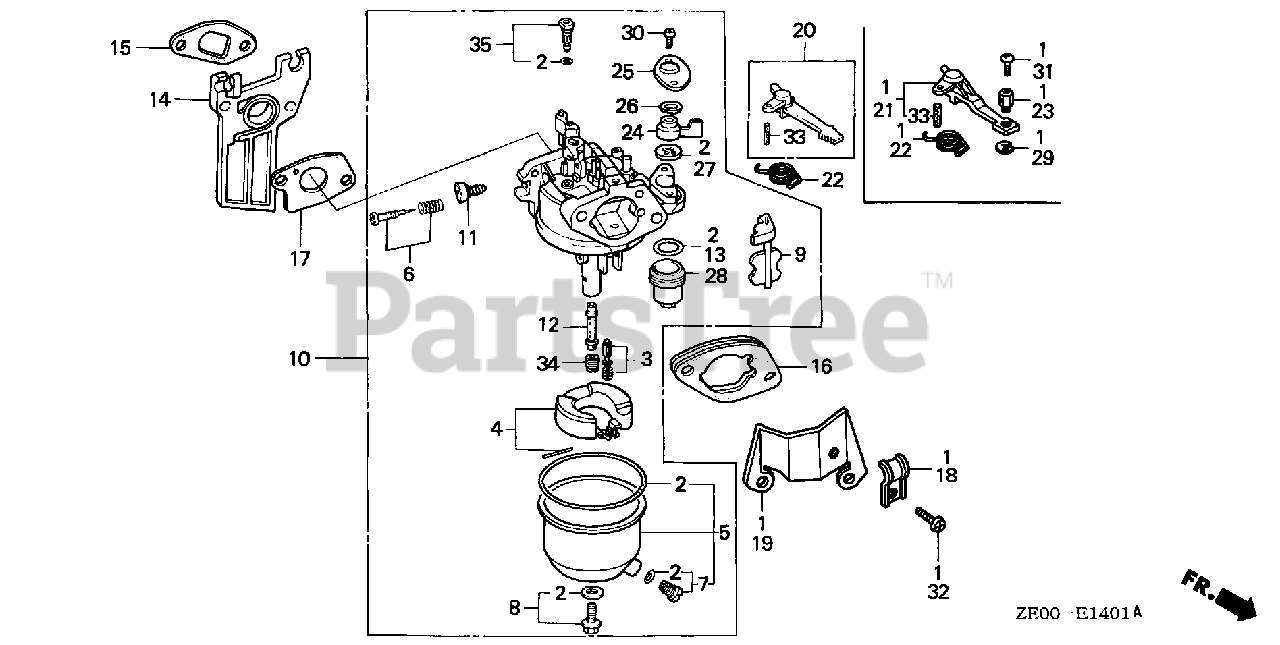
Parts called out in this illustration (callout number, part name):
2	GASKET SET
3	VALVE SET, FLOAT (SEAT NOT INCLUDED)
4	FLOAT SET
5	CHAMBER SET, FLOAT
6	SCREW SET, PILOT
7	SCREW SET, DRAIN
8	SCREW SET
9	CHOKE SET
9	CHOKE SET (NOT AVAILABLE)
10	CARBURETOR ASSY. (BE01B G) (W/STRAINER)
10	CARBURETOR ASSY. (BE01C A)
10	CARBURETOR ASSY. (BE01C C)
10	CARBURETOR ASSY. (BE01C D) (NOT AVAILABLE)
10	CARBURETOR ASSY. (BE01C F)
11	SCREW, THROTTLE STOP
12	NOZZLE, MAIN (NOT AVAILABLE)
12	NOZZLE, MAIN
13	GASKET, FUEL STRAINER CUP
14	INSULATOR, CARBURETOR
15	GASKET, INSULATOR
16	SPACER, CARBURETOR
17	GASKET, CARBURETOR
20	LEVER, CHOKE (STD)
24	LEVER, VALVE
25	PLATE, LEVER SETTING
26	SPRING, PETCOCK LEVER
27	GASKET, PETCOCK
28	CUP, FUEL STRAINER
30	SCREW, PAN (3X8)
33	PIN, SPRING (2X12)
34	JET, MAIN (#55)
34	JET, MAIN (#58)
34	JET, MAIN (#60)
34	JET, MAIN (#62)
35	JET SET, PILOT (#35)
